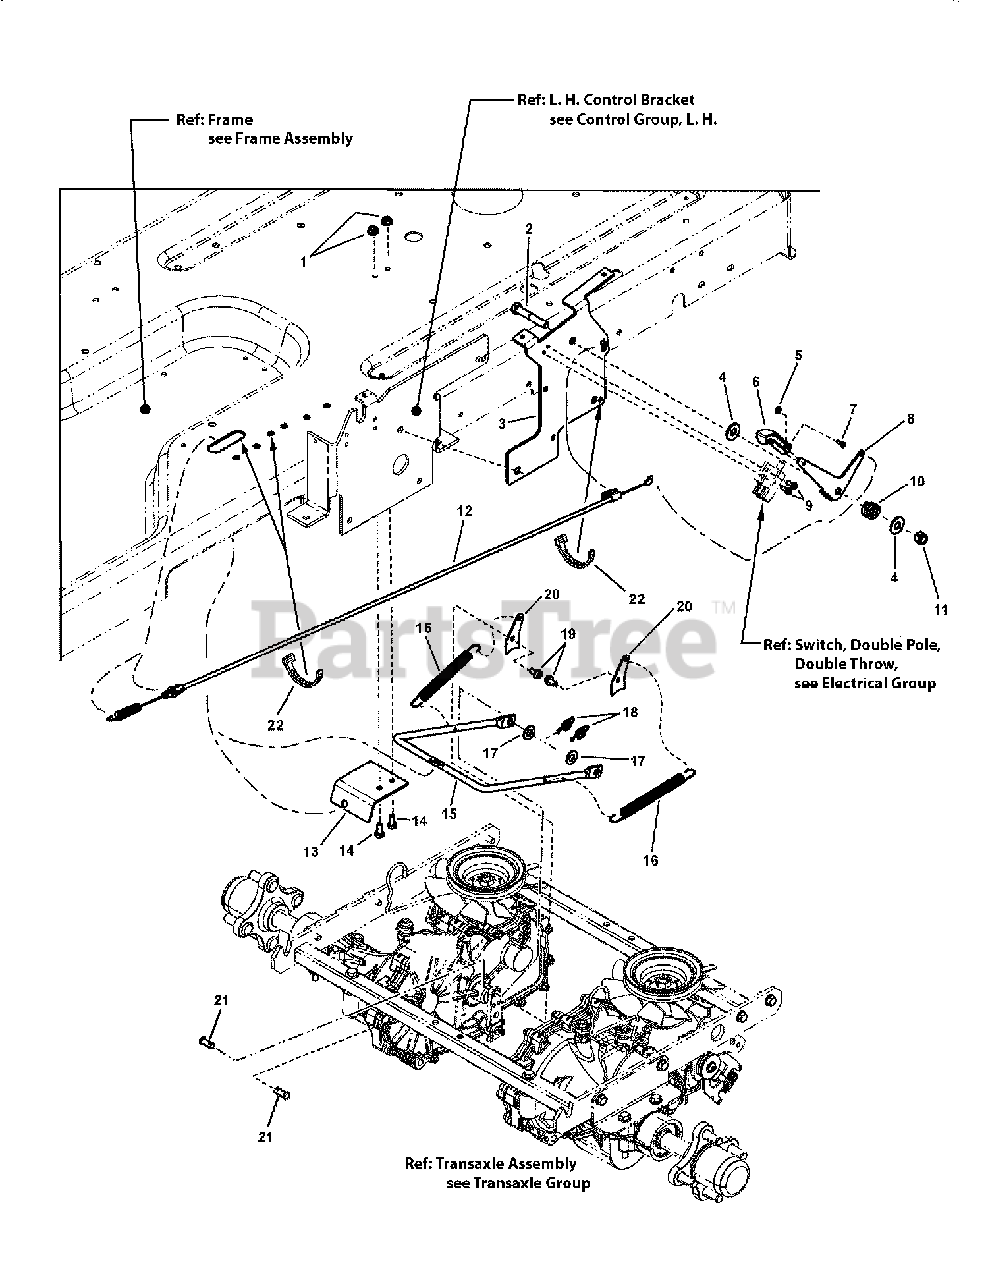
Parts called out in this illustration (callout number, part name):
1	NUT, 1/4-20 Hex Flange Lock, Black
2	SCREW, 3/8-16 x 2-1/4" Hex Head Cap, GR 5, YZ
3	BRACKET, Lever, Park Brake
4	WASHER, 3/8" Flat
5	NUT, #8-32 Hex, GR 2B
6	LEVER, Throttle Control
7	SCREW, #8-32 x 3/8" Cross Recess Filister Head, GR 2
8	LEVER, Brake, Park
9	SCREW, #10-24 x 1/2" Hex Washer Self-Tap, Torx
10	SPRING, Friction Pack
11	NUT, 3/8-16 Hex Nyloc, YZ
12	CABLE, Park Brake, RZT
13	BRACKET, Cable, Park Brake
14	SCREW, 1/4-20 x 5/8" Hex Head Cap, GR 5
15	ROD, Park Brake, ZT-2800
16	SPRING, Extension, .562 OD x 4.250 Long x .049 Wire
17	WASHER, 3/8" Flat (SAE)
18	COTTER PIN, 5/16" Self-Lock
19	SCREW, 1/4-20 x 1/2" Hex Washer Self-Tap
20	TAB, Spring, Park Brake
21	CLEVIS PIN
22	CABLE TIE, 7"
